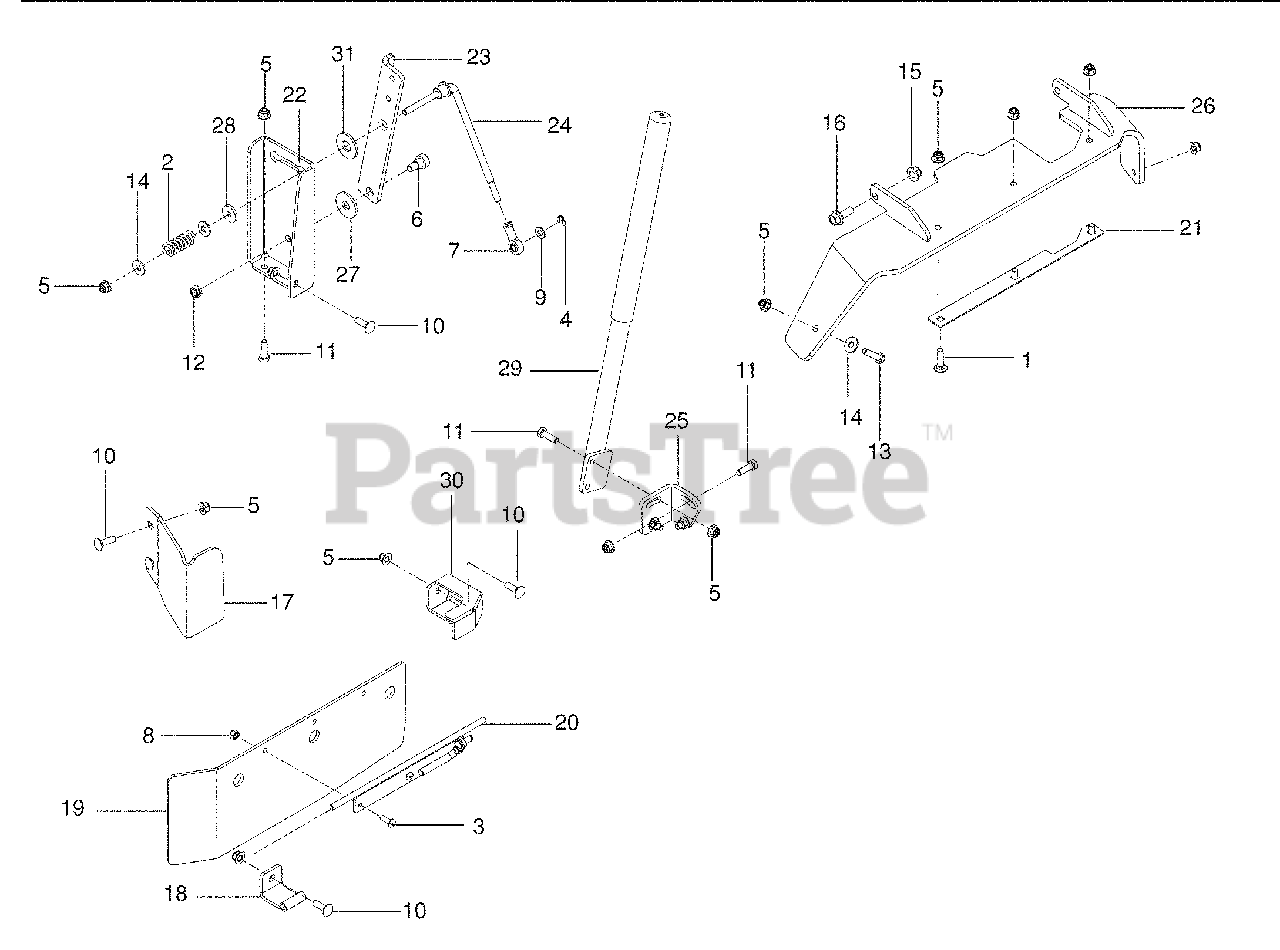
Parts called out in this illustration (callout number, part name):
1	RHSNB 5/16-18 x 1¼
3	SCREW ¼-20 x ¾ RD HD GR2
4	RETAINING RING
5	NUT 5/16-18 HEX FLANGE NYLOC
6	SHLDER BOLT 3/8-16 x 3/8 SKT HD
7	ROD END RH
8	NUT ¼-20 HEX NYLOC
9	WASHER 5/16 SAE FLAT
10	SHLDER BOLT 5/16-18 x 1 RD HD
11	HCS 5/16-18 x 1
12	NUT 3/8-16 HEX CNTRLK
13	HCS 5/16-18 x 1¼
14	WASHER, 5/16 STD FLT
15	NUT 3/8-16 HEX FLG NYLOC
16	HHFS 3/8-16 x 1
17	BLOCKER PLATE
18	PIVOT MOUNTING
20	HINGE PLATE
21	REINFORCEMENT PLATE
22	MOUNTING BRACKET
24	GATE PIVOT
25	BRACKET, HANDLE SWIVEL
26	CHUTE MOUNT
27	WASHER, FRICTION ½
28	WASHER, FRICTION 5/16
29	HANDLE ASSY w/ GRIP
30	PIVOT GUARD
31	WASHER, FRICTION 5/8 NOM ID
